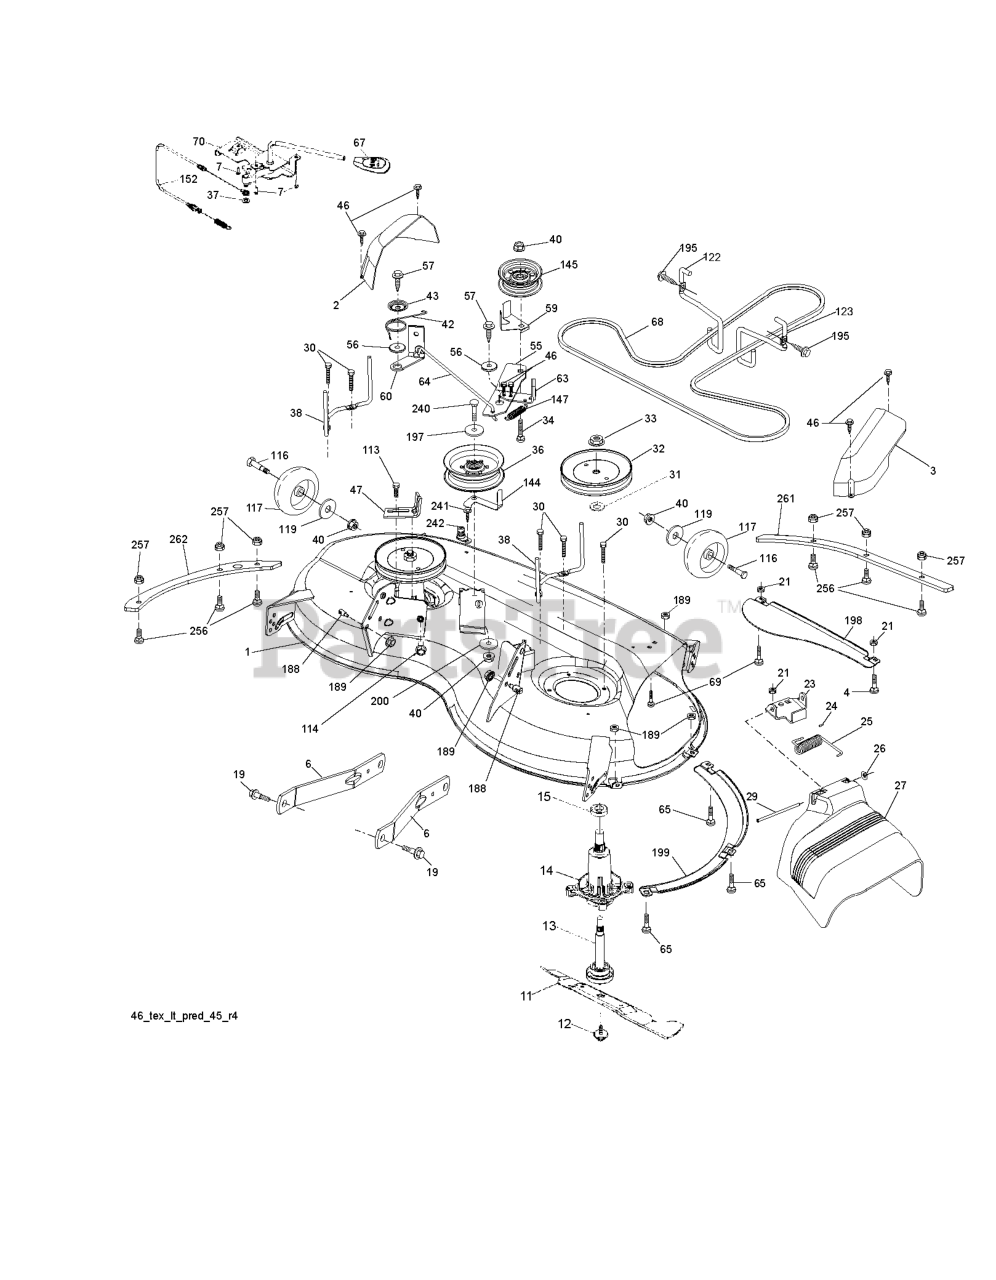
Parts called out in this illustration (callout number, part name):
1	DECK.SVC.46"405050X668
1	KIT SVC DECK WELDMENT
1	RP DECK.WELDMENT.46"(2GA.WHL)
1	DECK.SVC 46" 441616X498 GREY
2	COVER.MANDREL.LH.46"
3	COVER.MANDREL.RH.46"
4	SCREW HEXAGON HEAD SCREW 5/16-
4	Bolts
4	HCS 5/16C X 3/4
6	ARM.SUSPENSION.MOWER.R
7	SCREW.#10 X 0.750.BOS
11	BLADE.MOWER.46".HI.LIFT
12	SCREW.SEMS.7/16-20X1.HEX.HEAD
12	BOLT.WASHER.ASM.7/16-2
13	SHAFT.ASM.MDRL.N/GREASE.38
13	SHAFT ASM.MNDRL.N/GREASEABLE
14	KIT.MANDREL.NONGREASE.TALL
14	RP.HOUSING.MANDREL.4PT.
15	BEARING.MANDREL.TOP.EXTENDED
15	BEARING
19	BOLT.SHOULDER
23	BRKT.DEFLECTOR.38"2005+
24	CAP-SLEEVE LT
25	SPRING.TORSION.DEFLECT
26	NUT PUSH M
27	SHIELD.DEFLECTOR.MOWER.46"BLAC
29	ROD.HINGE
30	BOLT.HEX.WASHR.HED.313-18X1.19
31	WASHER.SPACER.MANDREL
32	PULLEY.MANDREL.5.438.PD
33	NUT.FLANGE.LOCK.TOP
34	GSPW Bolts
34	BOLT.3/8-16X1.50
36	PULLEY.IDLER.2006
37	WASHER PLAIN WASHER 3/8 X 0.08
37	WASHER
38	KEEPER.BLT.PNT.MNDRL.PULL.6.25
38	KEEPER.BELT.MANDREL.PULLEY
40	NUT LOCK FLG 3/8-16 UNC
42	SPRING.TORSION.BRAKE
43	SRPING.TORSION.RETAINE
46	SCREW.1/4-20X5/8
47	BRKT.CLUTCH.CABLE
56	SPACER.RETAINER
57	SCREW 3/8-16X1
59	GUARD, BELT
60	ARM BRAKE MOWER RH 38"
63	ARM BRAKE MOWER
64	LINKAGE BRAKE
65	BOLT ROUND HEAD SQUARE NECK BO
67	HANDLE.CLUTCH.CABLE.LT
68	V-BELT
70	CLUTCH.ASM.CABLE.HUSQ.TEX
70	CLUTCH.ASM.MANUAL.YT.PREDATORQ
113	BOLT.5/16HEX.WHS.HD
114	BOLT.5/16HEX.WHS.HD
116	BOLT.SHOULDER.3/8-16X3-5/8.
117	WHEEL.GAUGE.RALLY
119	WASHER.5/16.FLAT.STE.STD.
122	KEEPER BELT ENGINE LH
123	KEEPER BELT RH
144	KEEPER.BELT.MOWER
145	PULLEY.IDLER.48"PRIMARY
147	SPRING RETURN
152	CABLE.CLUTCH.CABLE.W/SPRING
152	CABLE.MECHANICAL.CLUTCH
188	STUD.FASTNER.W/ANTI-ROTATE
188	STUD.W/"D"ANTI-ROTATION
195	SCREW, 3/8-16X3/4
197	GSPH
198	BAFFLE CENTER FRONT
199	BAFFLE FRONT RH
200	WASHER.13/32 X 1 X 1/2.11GUARD
240	BOLT-HEX EAK
241	SCREW.TT.#10-32X.5.3/8.FLANGE
242	PORT.WASHOUT
256	RHSNB, 1/4-20 X 1, GR5
256	BOLT CUP HEAD SQUARE NECK BOLT
257	NUT HEX_LRG FLG_1_4-20_LOCK
257	NUT T
261	PLATE.REINF.DECK.46".FRONT.BLK
262	PLATE.REINF.DECK.46".SIDE.BLK
